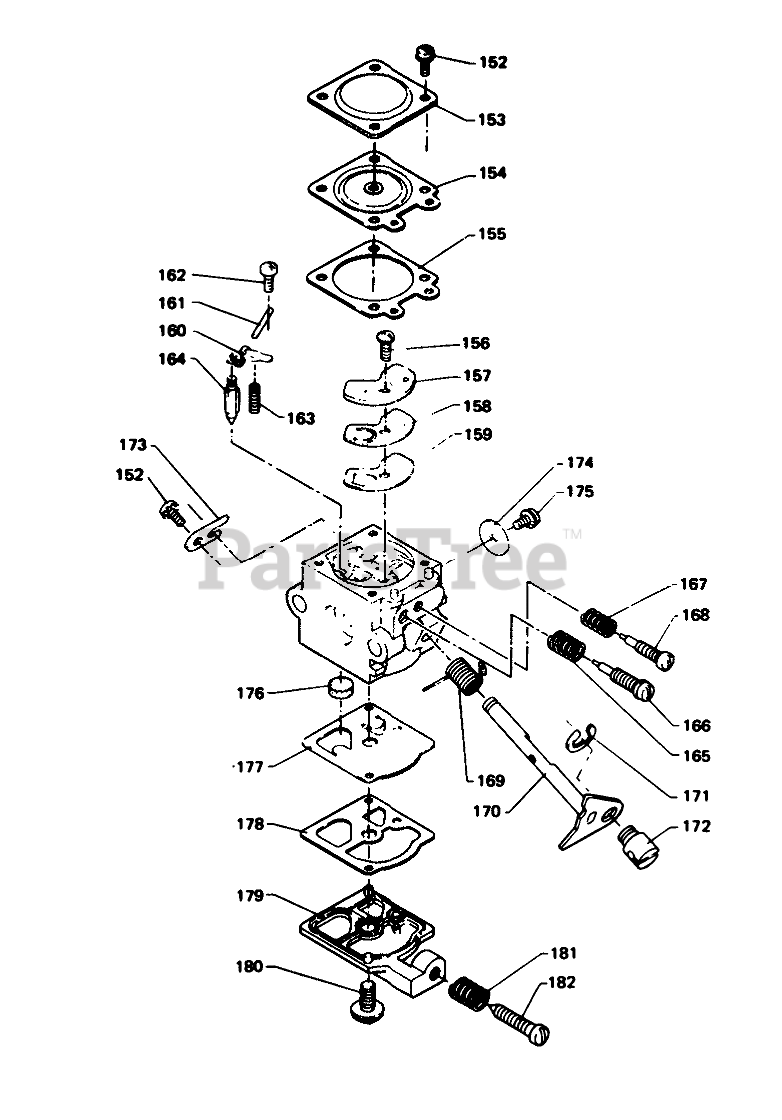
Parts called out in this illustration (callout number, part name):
152	Screw
153	Cover, Diaphragm
154	METERING DIAPHRAGM
155	Gasket, Diaphragm
156	Screw-Circuit Plate
157	Plate, Circuit
158	Diaphragm Circuit Plate
159	Gasket-Circuit Plate
160	Lever, Metering
161	Metering Lever Pin
162	Screw-Metering Pin
163	METERING LEVER SPRING
164	INLET NEEDLE VALVE
169	Spring-Throttle Lever
170	Shaft Ass-y. Throttle
172	Swivel
173	Clip Throttle Shaft
174	Valve-Throttle
175	Screw
176	Screen Inlet
177	Diaphragm Fuel Pump
178	PUMP GASKET
179	Cover, Fuel Pump
180	Screw
181	Spring, Idle Screw
182	Screw, Idle Adjust
